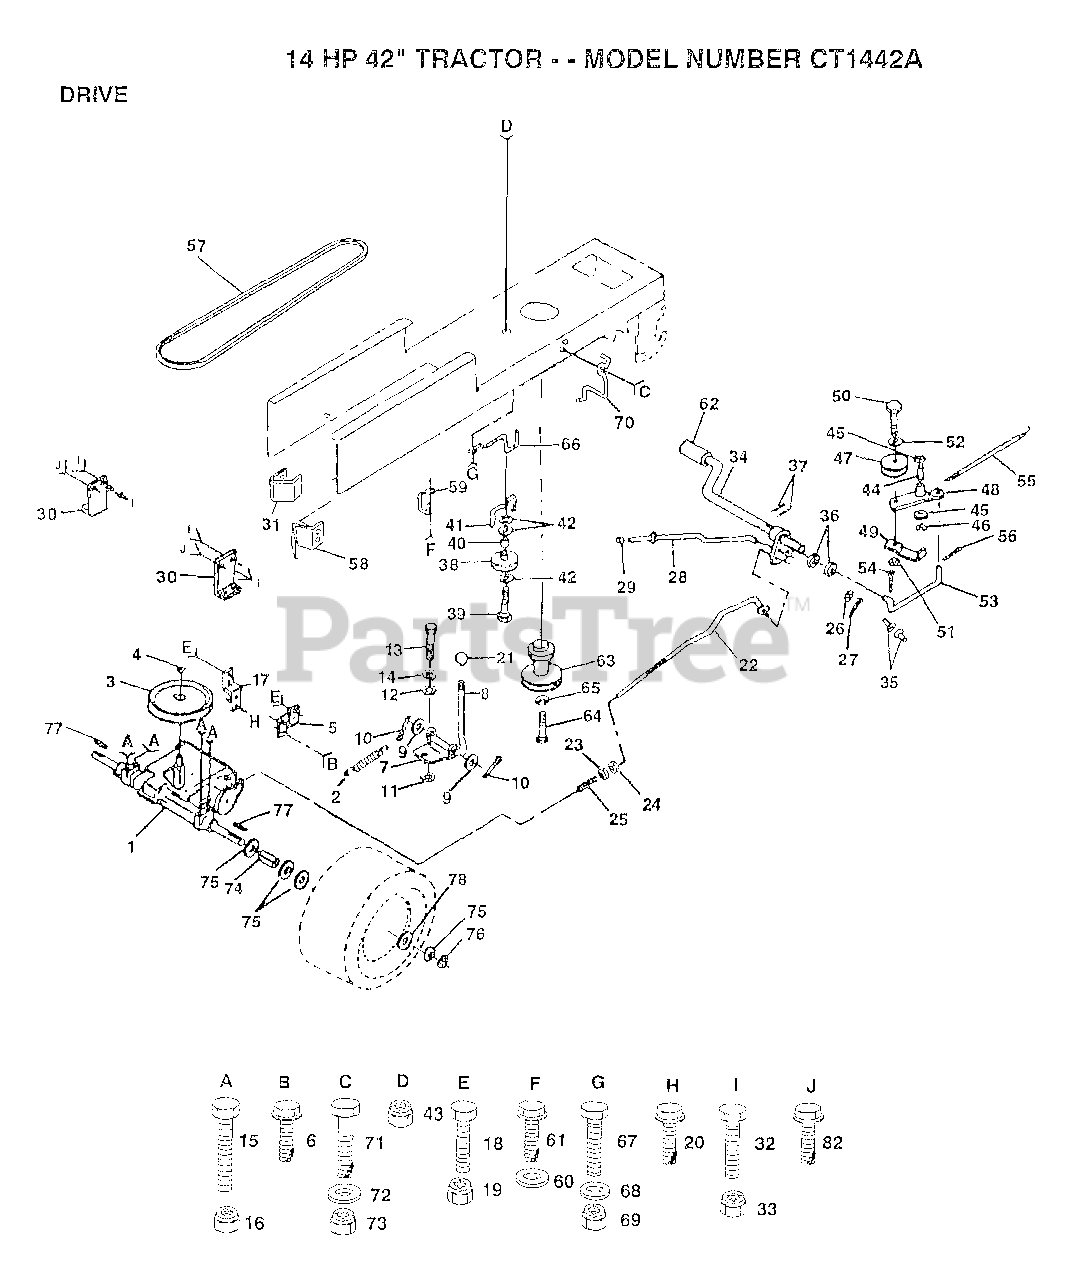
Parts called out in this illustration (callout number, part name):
3	PULLEY TRANS
5	STRAP TORQUE
6	SCREW
8	SHIFT ROD
9	WASHER
10	PIN COTTER 1/8
11	WASH-SHFT PLT LT
12	WASHER LT
14	LOCKWASHER
15	BOLT
17	STRAP TORQUE
20	SCREW
21	CONTROL KNOB LT
22	BRAKE ROD
23	NUT
24	NUT
25	SPRING ROD LT
26	WASHER
27	COTTER PIN
28	PARKING BRAKE ROD
30	TRANSAXLE MTG BKT
31	"KEEPER,BELT LH T"
32	BOLT
35	NYLON BEARING
36	WASHER LT
38	PULLEY.IDLER.FLAT
39	BOLT
40	SPACER T
41	BELT KEEPER LT
42	WASHER
44	"LY, BEARING"
45	WASHER LT
46	KLIP RING
48	ARM IDLER
49	RETAIN BELT
52	WASHER
53	"LINK, CLUTCH T"
54	COTTER PIN
55	"SPRING, RETURN LT"
56	COTTER PIN
57	BELT.V.GDRIVE.95
58	"KEEPER,BELT RH T"
60	WASHER
61	SCREW
62	PEDAL COVER T
64	"BOLT,HEX"
65	LOCKWASHER
66	KEEPER.BELT.ENG.L
67	BOLT
68	WASHER
70	KEEPER BELT ENG
71	BOLT
72	WASHER
74	SPACER LT
75	WASHER
76	E-RING LT
77	SQUARE KEY
78	WASHER
82	SCREW
